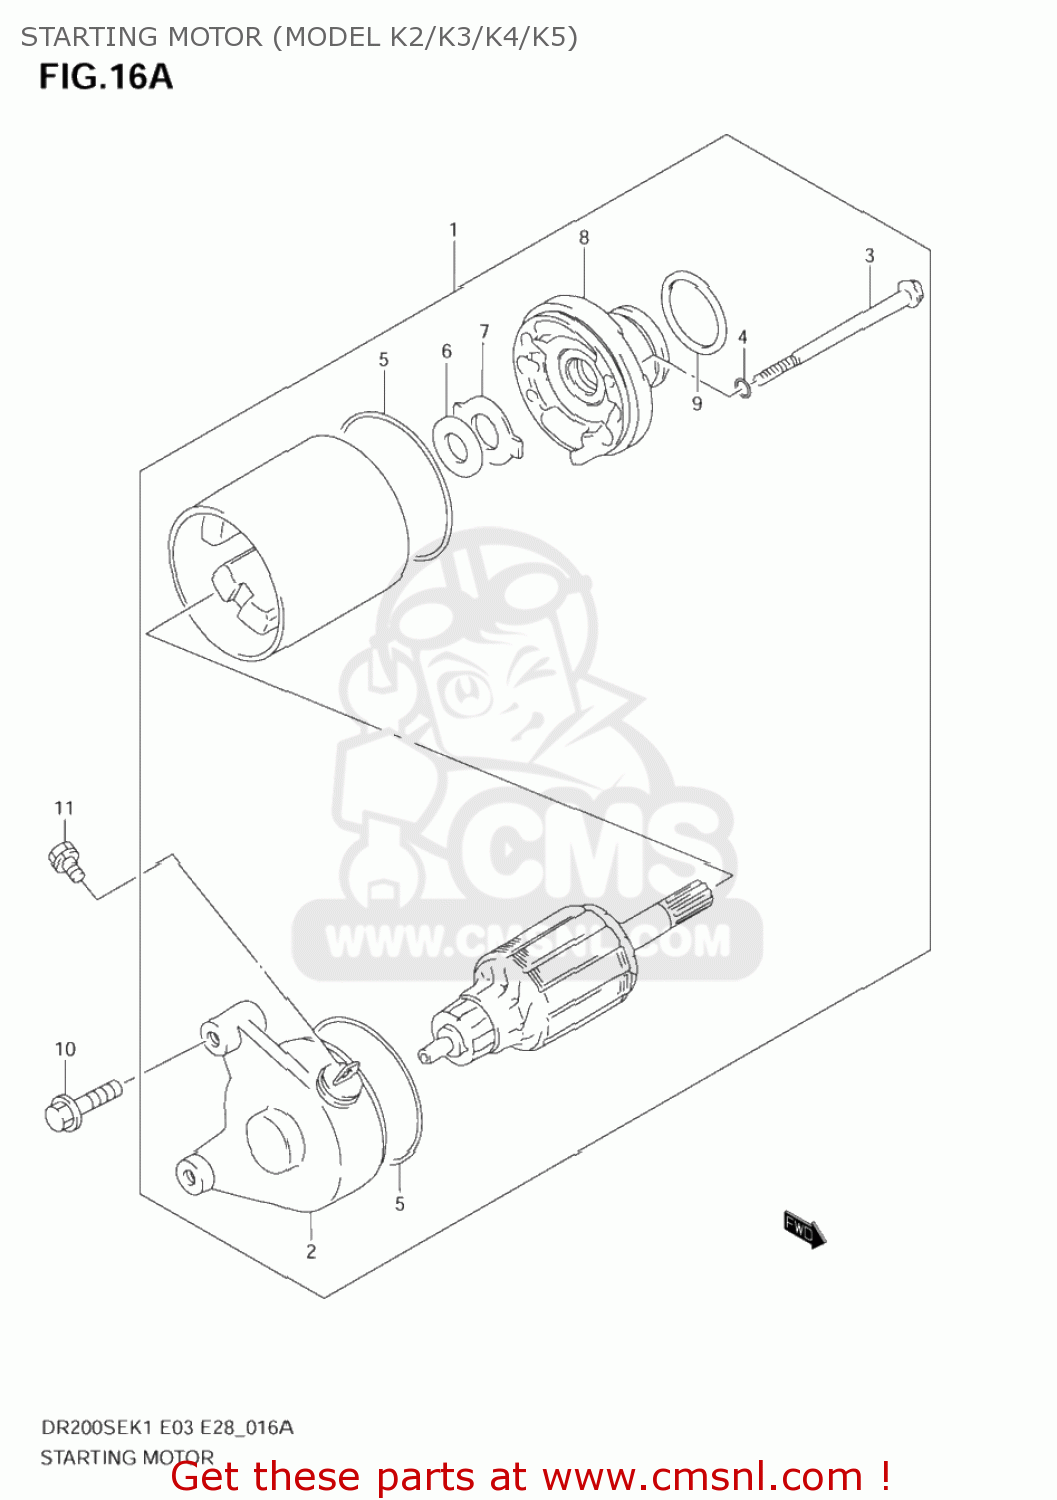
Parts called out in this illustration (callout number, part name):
1	MOTOR ASSY,STARTING
2	FRAME ASSY,COMMUTATOR END
3	BOLT
4	O RING
5	O RING
6	SHIM
7	PLATE,LOCK
8	BRACKET
9	O RING(D:3,ID:24.5)
10	BOLT,G/S SWITC
11	SCREW(5X8)
